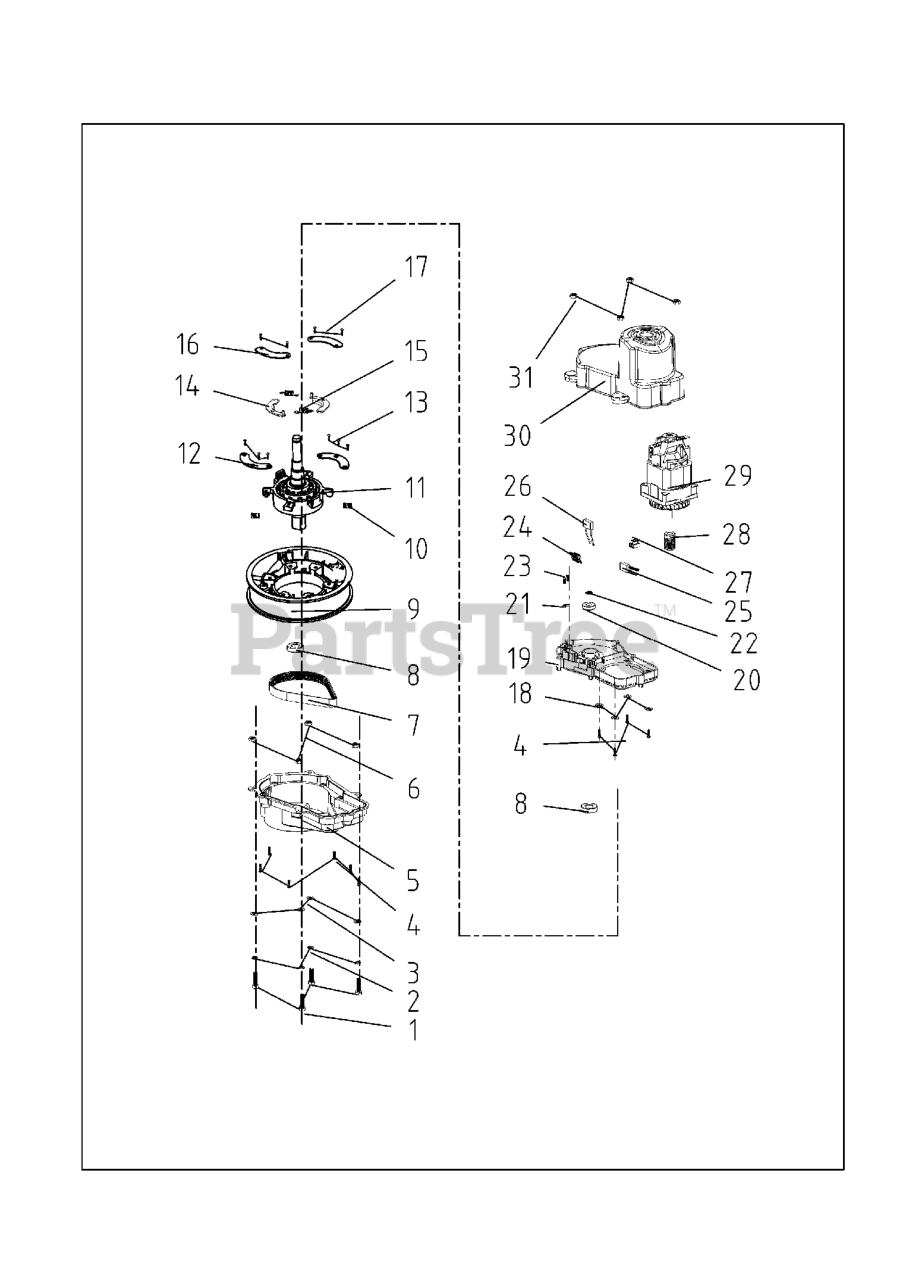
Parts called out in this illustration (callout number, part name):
2	SPRING WASHER
6	HEXAGON NUT #26800502301
31	NUT LOCKING
